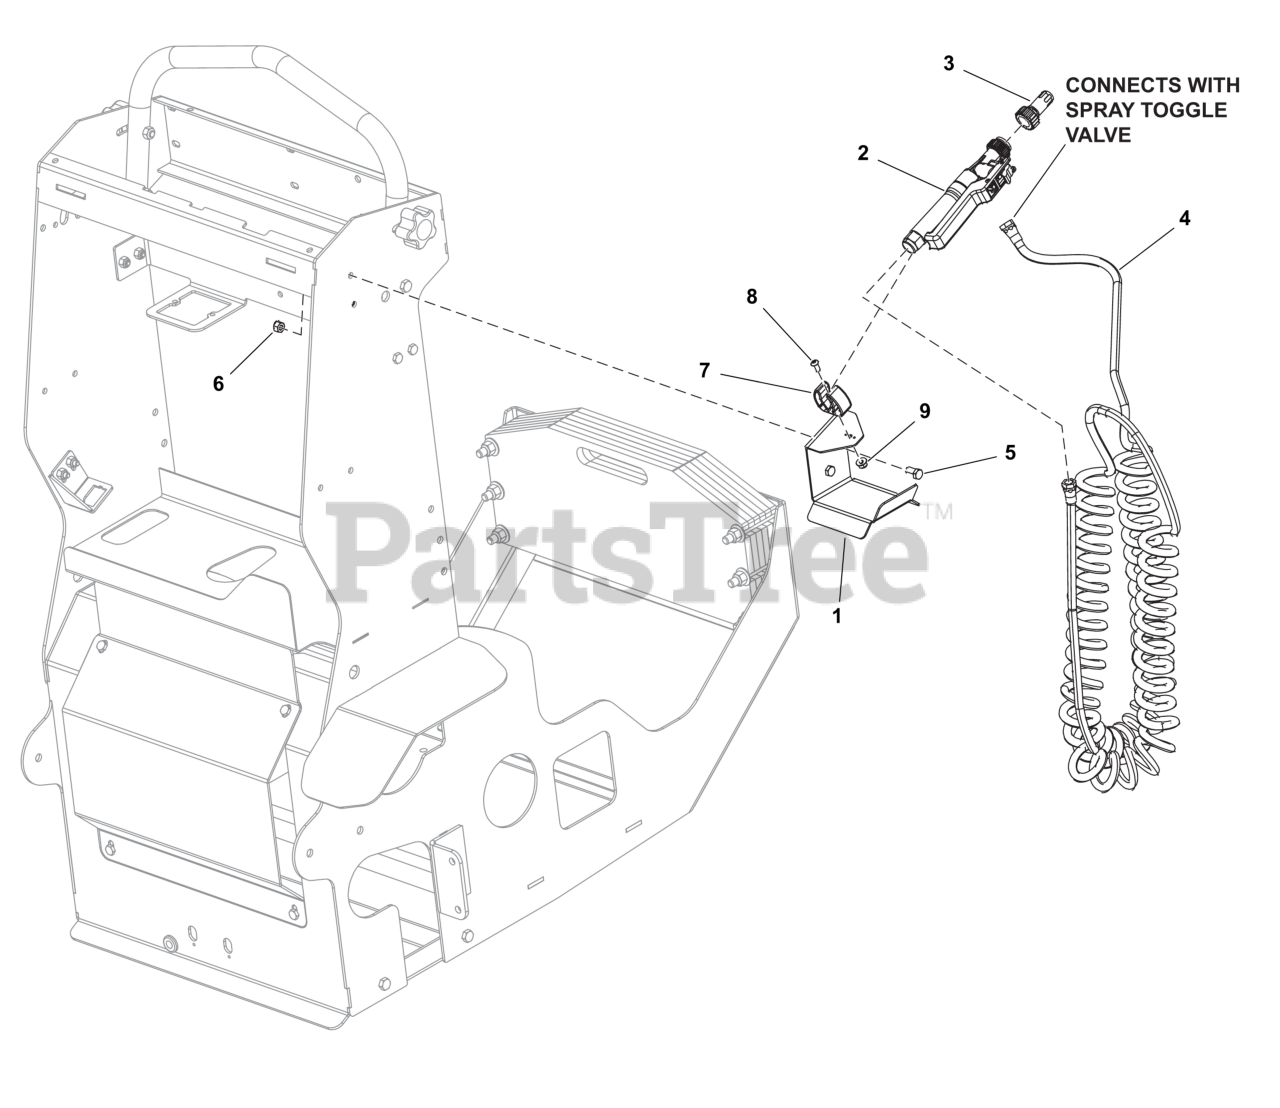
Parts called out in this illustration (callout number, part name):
1	BRACKET, COIL HOSE HOLDER
2	SPRAY GUN, 1/4 FPT
3	NOZZLE TIP, ADJUSTABLE SPRAY, STANDARD
4	HOSE, COIL 25 FT
5	SCR-CAP, HEX .250"-20 X .625" SS188
7	CLIP, .750" O.D. OIL DRAIN HOSE
8	SCR-CAP, BSH #10-24 X .500" SS188
9	NUT-HEX-NYLK, FLG .#10-24 SS188
